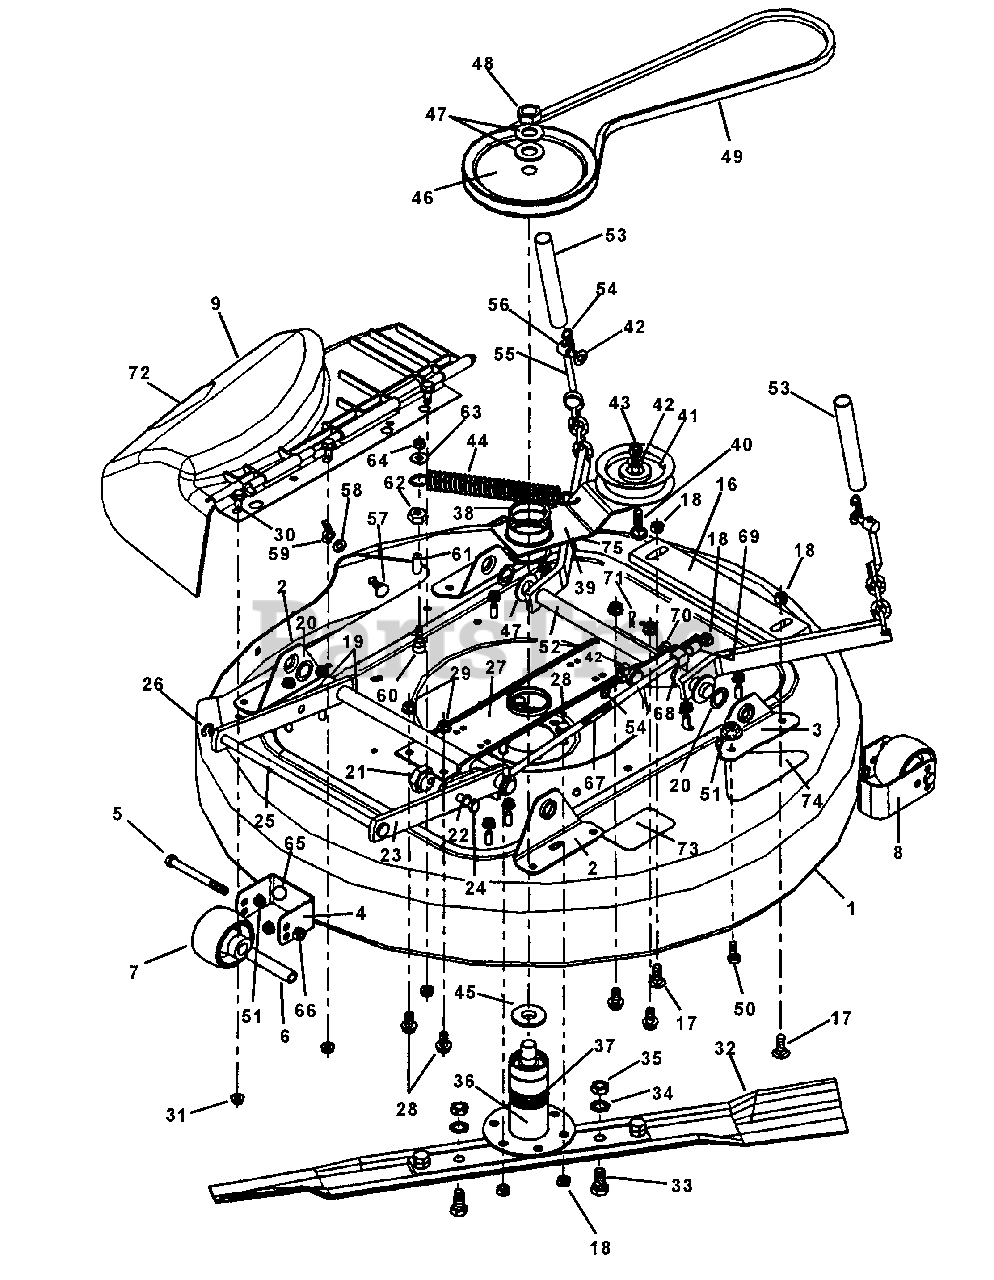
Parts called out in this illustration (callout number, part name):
1	DECK, 33"
2	BRACKET, Deck Lift Slotted
3	BRACKET, Deck Lift
4	BRACKET, Anti-Scalp Adj. Front
5	SCREW, 3/8-24 x 3/4" H.H. Cap
6	SPACER, 3" Long
7	WHEEL, Gage
8	BRACKET, Anti-Scalp Adj. Side
9	ASSM'Y. Chute 28 & 33" Discharge
16	BAR, Weight Rear
17	BOLT, 3/8-16 x 1" Carriage
18	NUT, 3/8-16 Hex Lock
19	ARM, Front Lift
20	WASHER, 3/4"
21	ECCENTRIC, Leveling
22	WASHER, 3/8" Internal Tooth Lock
23	ARM, Front Lift
24	SCREW, 3/8-24 x 1-1/4" H. H. Cap
25	ROD, Deck Support
26	RING, 7/16" Snap
27	BRACE, Spindle
28	BOLT, 3/8-16 x 3/4" Hex Flange Lock, Grade 5
29	NUT, 3/8-16 Hex Flange Lock
30	BOLT, 5/16-18 x 5/8" Hex Flange Lock, Grade 5
31	NUT, 5/16-18 Hex Flange Lock Grade 5
32	BLADE, 33" High Lift
33	SCREW, 1/2-20 x 1" H. H. Cap
34	WASHER, 1/2" Internal Tooth Lock
35	NUT, 1/2-20 Hex Jam
36	ASSEMBLY, Spindle
37	RING, 2" Tolerance
38	RING, 2" External Retaining
39	ARM, Idler
40	BOLT, 3/8-16 x 2" Carriage
41	IDLER, 4" O.D. Flat
42	WASHER, 3/8" Flat
43	NUT, 3/8-16 Hex Lock
44	SPRING, External
45	WASHER, Spindle
46	PULLEY, Spindle
47	WASHER, 25/32" Flat
48	NUT, 3/4-16 Hex Jam
49	BELT, HA 33" Deck
50	BOLT, 5/16-18 x 3/4" Hex Flange Lock
51	NUT, 5/16-18 Hex Flange Lock
52	ARM, Rear Lift
53	COVER, Chain
54	PIN, 3/32 x 1-1/2" Hair
55	ADJUSTER, Chain
56	SWIVEL, Adjustable
57	BOLT, 5/16-18 x 3/4" Carriage Grade 5
58	WASHER, 11/32" Grade 5
59	NUT, 5/16-18 Wing
60	BOLT, 5/16-18 x 1-1/2" Hex Flange Lock
61	SPACER, 11/32"
62	NUT, 5/16-18 Hex Lock
63	WASHER, 3/8" Flat
64	NUT, 5/16-18 Hex Lock
65	BOLT, 5/16-18 x 1/2" Carriage
66	NUT, 3/8-24 Hex Lock
67	ROD, Cutting Deck Timing
68	SWIVEL, Brake Link PM
69	SPACER, 25/64"
70	WASHER, 3/8"
71	PIN, Hair
72	DECAL, Caution
73	DECAL, Caution
74	DECAL, Hi-Vac
75	DECAL, Chute/Deflector
